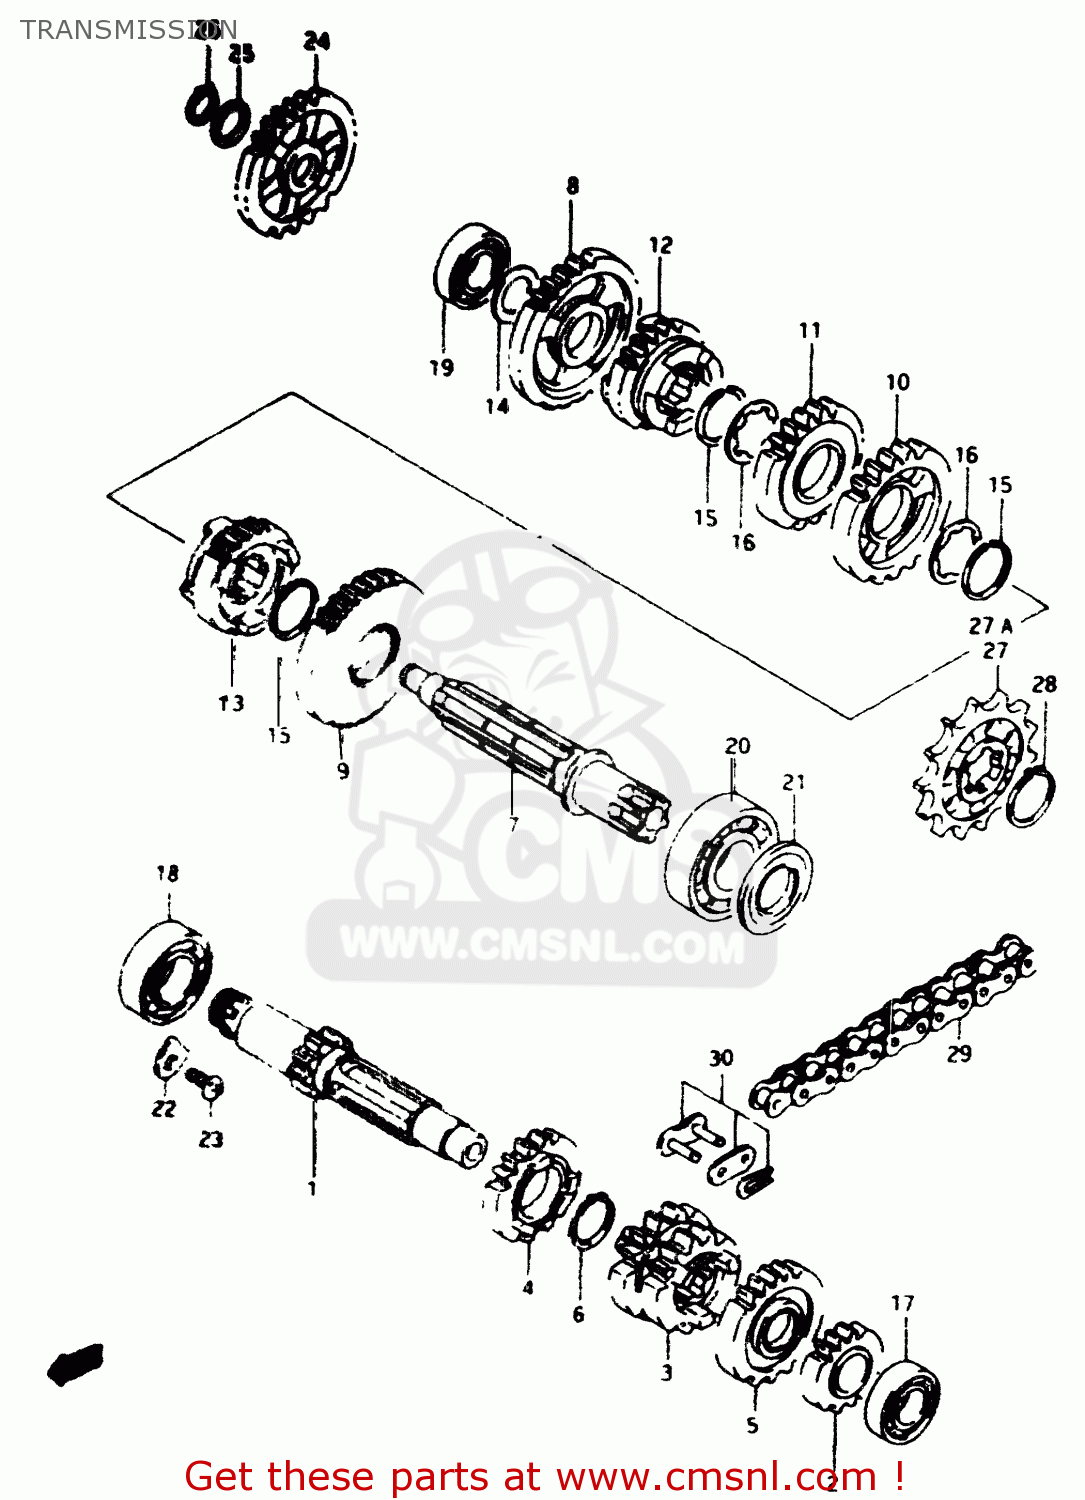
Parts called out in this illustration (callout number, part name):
1	SHAFT,COUNTER (NT:11)
2	GEAR,2ND DRIVE (NT:15)
3	GEAR,THIRD/FOURTH DRIVE
4	GEAR,FIFTH DRIVE
5	GEAR,6TH DRIVE
6	CIRCLIP
7	SHAFT,DRIVE
8	GEAR,FIRST DRIVEN
9	GEAR,SECOND DRIVEN
10	GEAR,THIRD DRIVEN (NT:22)
11	GEAR,FOURTH DRIVEN (NT:20)
12	GEAR,FIFTH DRIVEN
13	GEAR,SIXTH DRIVE (NT:23)
14	WASHER,THRUST
15	CIRCLIP
16	WASHER,LOCK
17	BEARING
18	BEARING(20X42X12)
19	BEARING
20	BEARING(20X47X14)
21	OIL SEAL (20X35X5)
22	RETAINER
23	SCREW
24	GEAR,KICK STARTER IDLE(NT:24)
25	SHIM
26	CIRCLIP,12 MM
27	SPROCKET,ENGINE(NT:14)
27A	SPROCKET,ENGINE(NT:13)
28	CIRCLIP
29	CHAIN,DRIVE(428G2X118L)
30	JOINT SET,CHAIN
